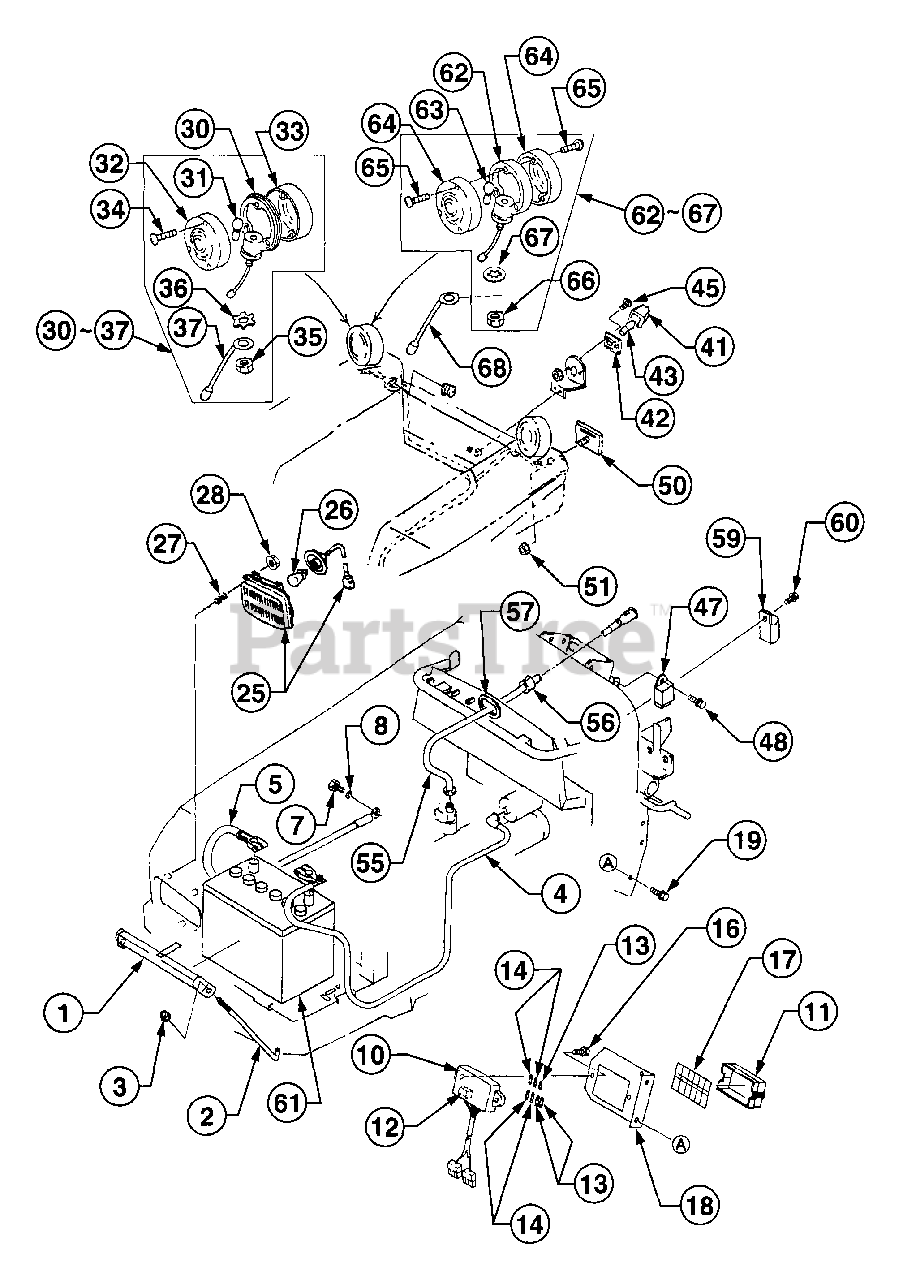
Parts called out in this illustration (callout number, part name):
1	Clamp Battery
4	Cable, Battery
5	Cable, Battery
10	Body Assy
19	Bolt, w/Washer
25	Lamp Unit
34	Screw
36	Washer, Tooth
41	Lens
48	Bolt, w/Washer
55	Cable, Flexible
61	Battery-500 CCA
63	Bulb
